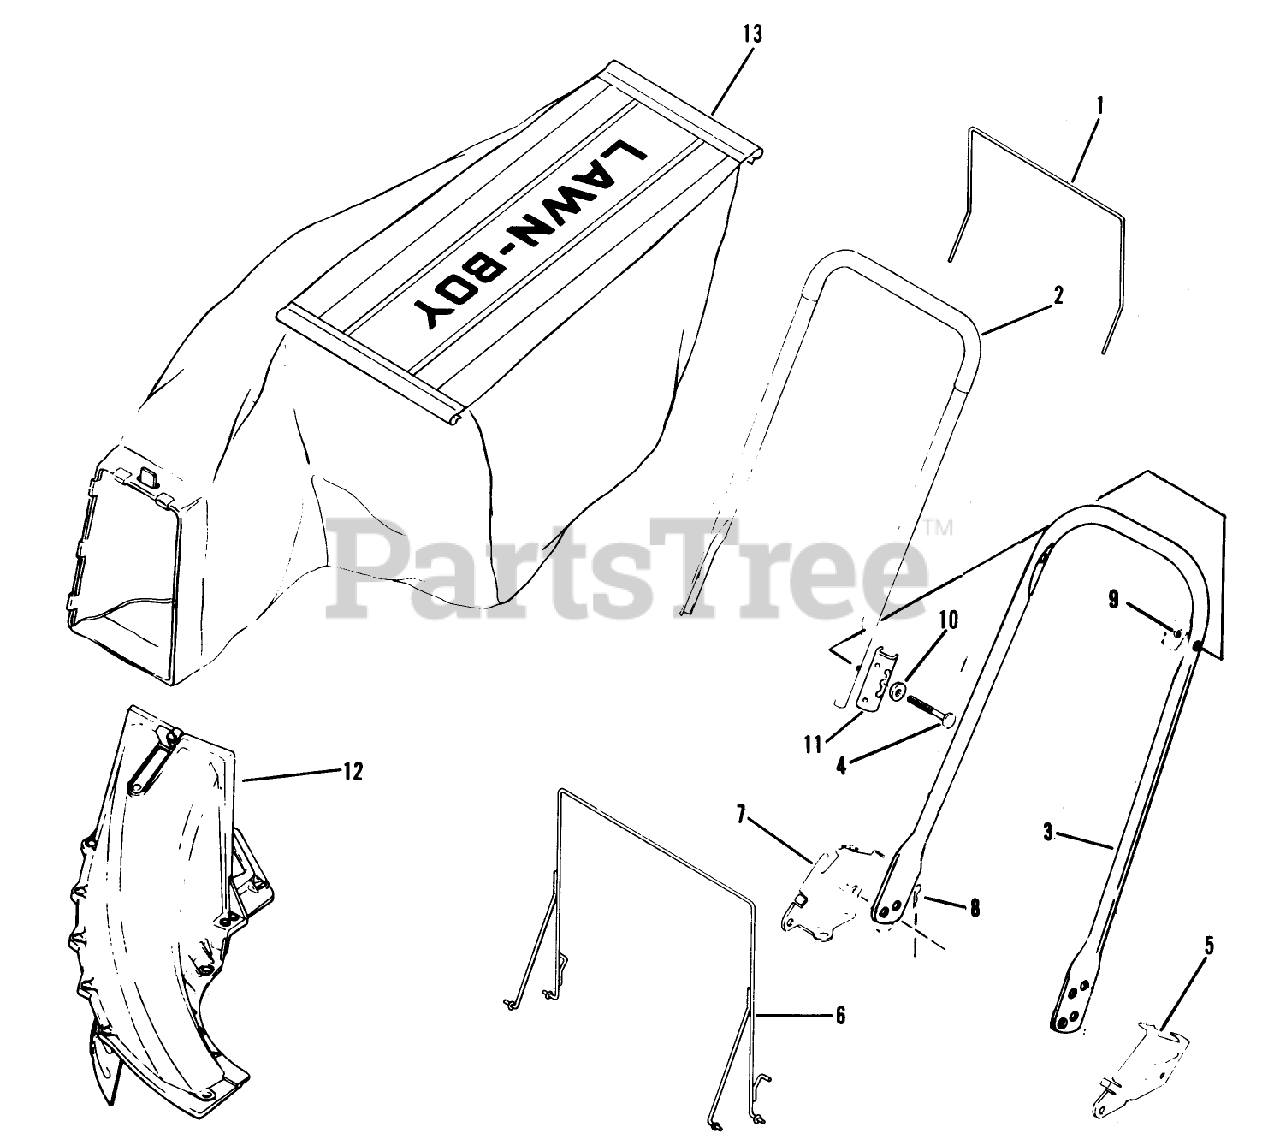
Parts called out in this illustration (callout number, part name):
4	SCREW - USE 137-3042
8	HAIR PIN
9	LOCKNUT E
10	WASHER-CURVED
11	BRACKET R/B 613462
